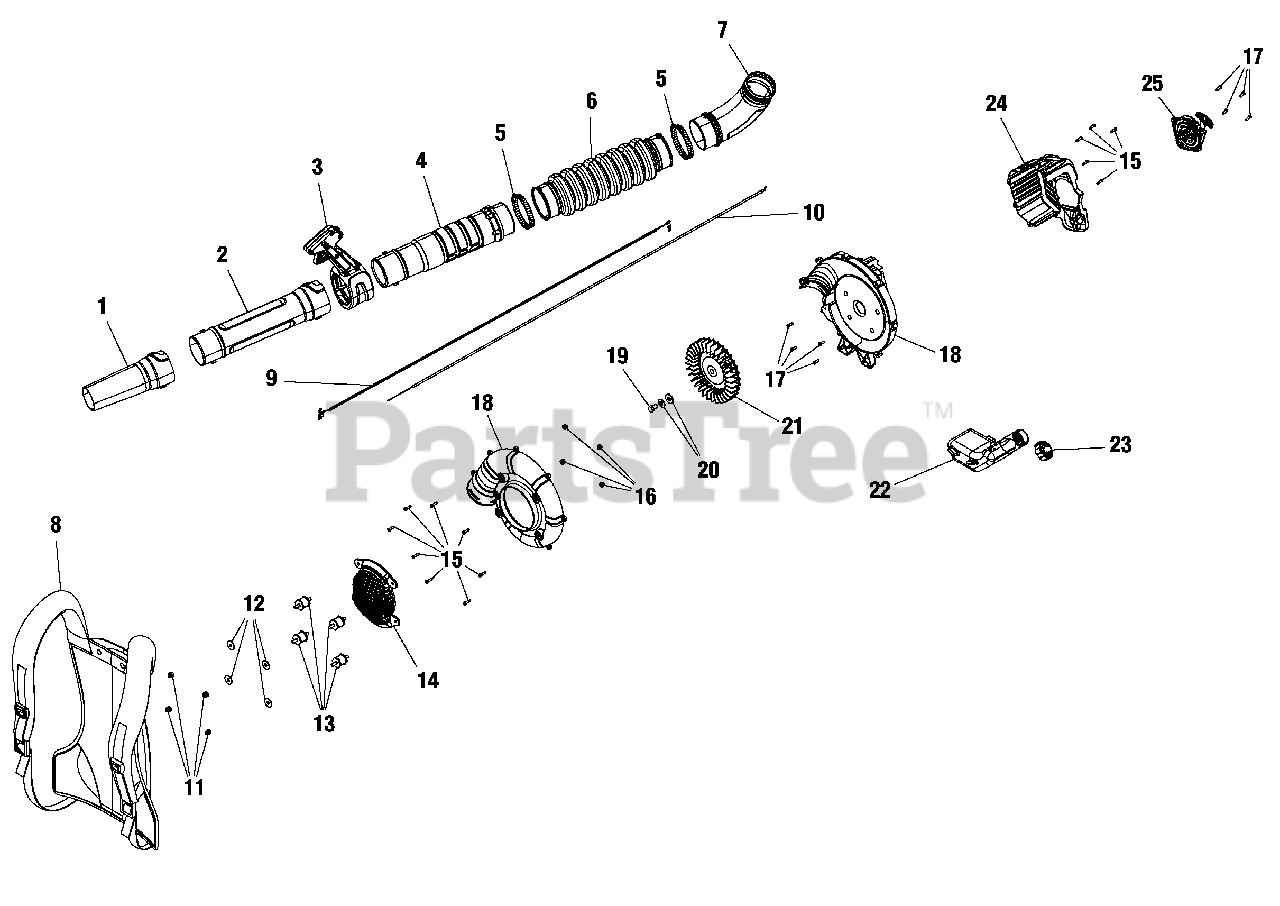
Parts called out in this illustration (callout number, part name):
2	Lower Blower Tube
3	Throttle Grip Assembly
4	Upper Blower Tube
5	Clamp
6	Flex Tube
7	Elbow
8	Harness
9	Lead Wire
10	Throttle Cable
11	Nut
12	Washer
13	Insulator Mount
14	Intake Cover
15	Screw
16	Nut
17	Screw
18	Impeller Housing Assembly
19	Bolt
20	Impeller Hardware
21	Impeller
22	Fuel Tank Assembly
23	Fuel Cap
24	Housing Assembly
25	Starter Assembly
